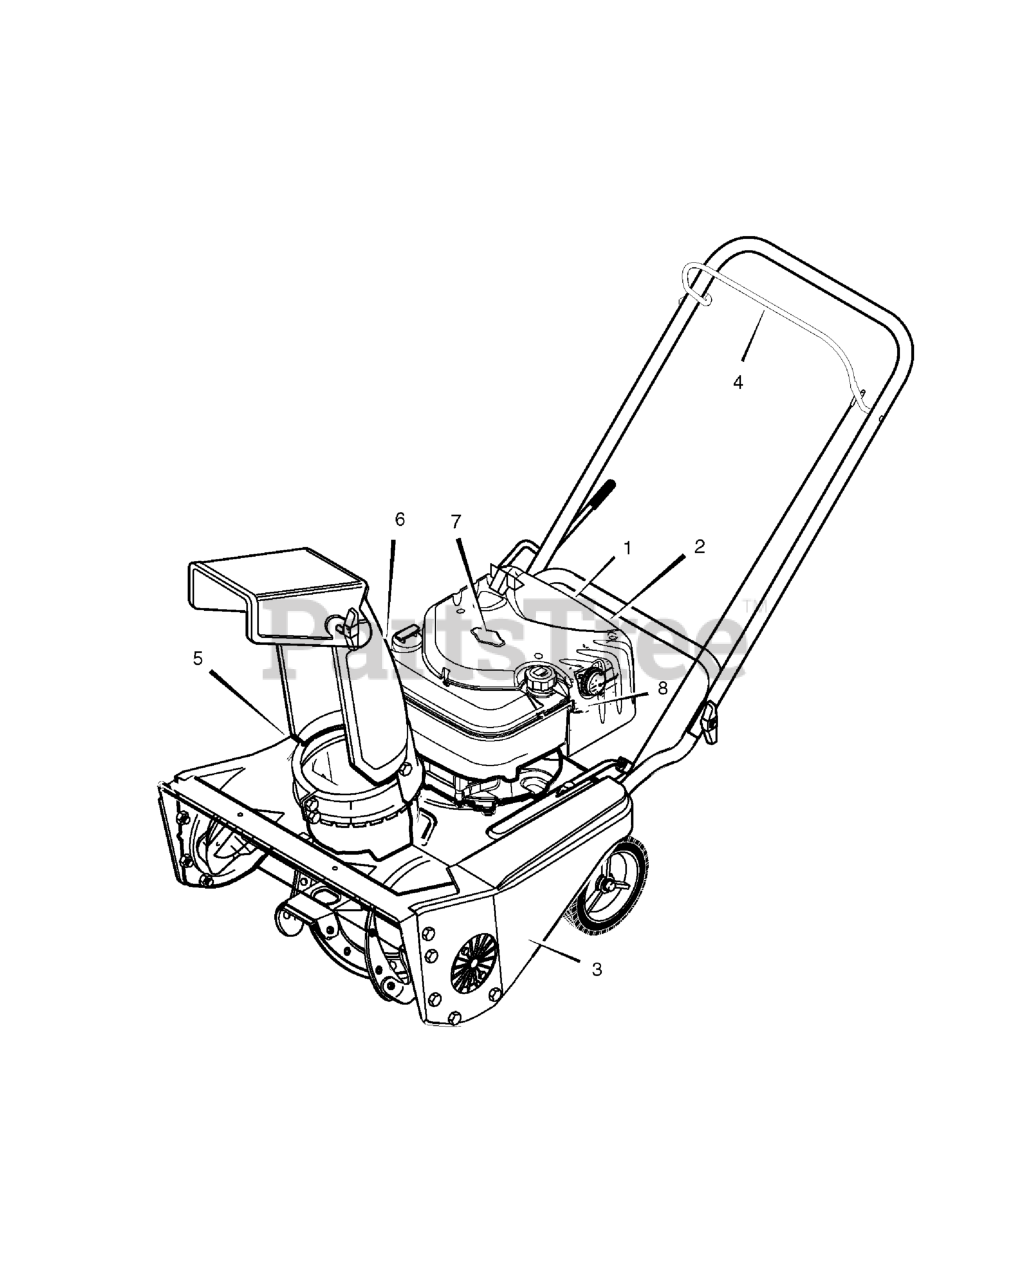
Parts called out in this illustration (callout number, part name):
1	Decal, 4hp / 21"
2	Decal, Choke
3	Decal, Belt Instruction (inside cover)
4	Decal, Auger Control Lever
5	Decal, Danger Auger (Foot)
6	Decal, Danger Chute (Hand)
7	Decal, Briggs & Stratton
8	Decal, Primer Bulb
